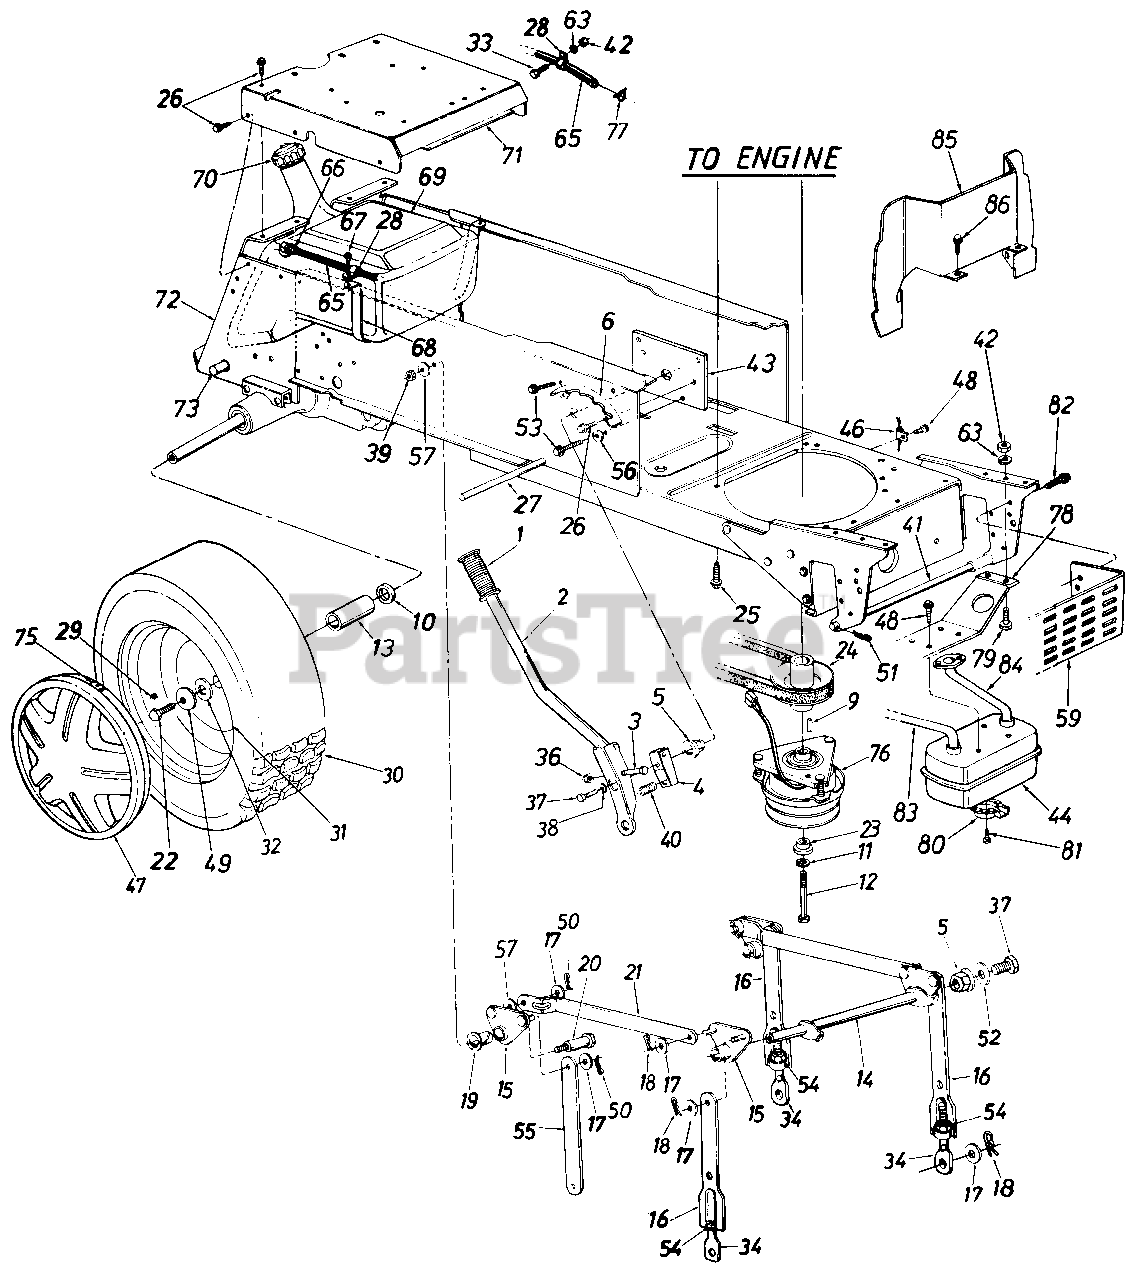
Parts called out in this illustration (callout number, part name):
1	Grip
2	Lift Handle Ass'y.
3	Hex Bolt 5/16-18 x 1.5" Lg.
4	Lift Shaft Drive
5	Plastic Hex Brg. 5/8" I.D.
9	Sq. Key 1/4" x 1" Lg.
10	Fl-Wash. .76" I.D. x 1.49" O.D.
11	L-Wash. 7/16" I.D.
12	Hex Bolt 7/16-20 x 3.75" Lg.
13	Sleeve .75" I.D. x 1.0" O.D.
14	Lift Shaft Ass'y.
15	Lift Pivot Brkt. Ass'y.
17	Fl-Wash. 1/2" I.D. x 1.00" O.D. x .090"
18	Hairpin Cotter
19	Nyliner 5/8" I.D. x .88" Lg.
20	Shld. Bolt 5/8" Dia. x .96" Lg. 3/8-16
23	Shoulder Spacer
24	Engine Pulley
25	Hex Wash. Hd. Scr. 3/8-16 x 1.25" Lg.
26	Hex Thd. Rolling Scr. 5/16-18 x .75" Lg.
27	Running Board Rod
29	Air Valve
32	Flat Washer .34" I.D.
33	Hex Bolt 1/4-20 x .62" Lg.
34	Eye Bolt Adj. Link 1/2-13 Thd.
36	Hex Cent. L-Nut 5/16-18 Thd.
37	Hex Bolt 5/16-24 x .62" Lg.
39	Hex Top L-Nut 3/8-16 Thd.
40	Compression Spring
41	Deck Connecting Rod
42	Hex Nut 1/4-20 Thd.
46	Mounting Clamp
47	Hub Cap
48	Hex Wash. Hd. TT-Tap Scr. 1/4-20 x .5" Lg.
49	Bell-Wash. .39" I.D.
50	Cotter Pin .09 Dia. x 1.0" Lg.
51	Int. Cotter Pin
52	Flat Wash. .34" I.D. x 1.12" O.D. x .125"
53	Hex Wash. Hd. AB-Tap Scr. 5/16-24 x .5" Lg.
54	Hex Nut 1/2-13 Thd.
56	Fl-Wash. .344" I.D.
57	Bell-Wash. .4" I.D. x 1.13" O.D.
59	Heat Shield
63	L-Wash. 1/4" I.D.
65	Fuel Line 46" Lg.
67	Hex AB-Tap Scr. 1/4 x .62" Lg.
68	Fuel Tank Strap
69	Gas Tank
75	Spring Clip
76	Electric Clutch
78	Muffler Mounting Brkt.
79	Hex Bolt 1/4-20 x .62" Lg.
80	Muffler Deflector
81	Hex Wash. Hd. F-Tap Scr. #8 x .32" Lg.
82	Hex Wash. Hd. TT-Tap Scr. 5/16"-18 x .62" Lg.
83	Exhaust Tube - R.H.
84	Exhaust Tube - L.H.
